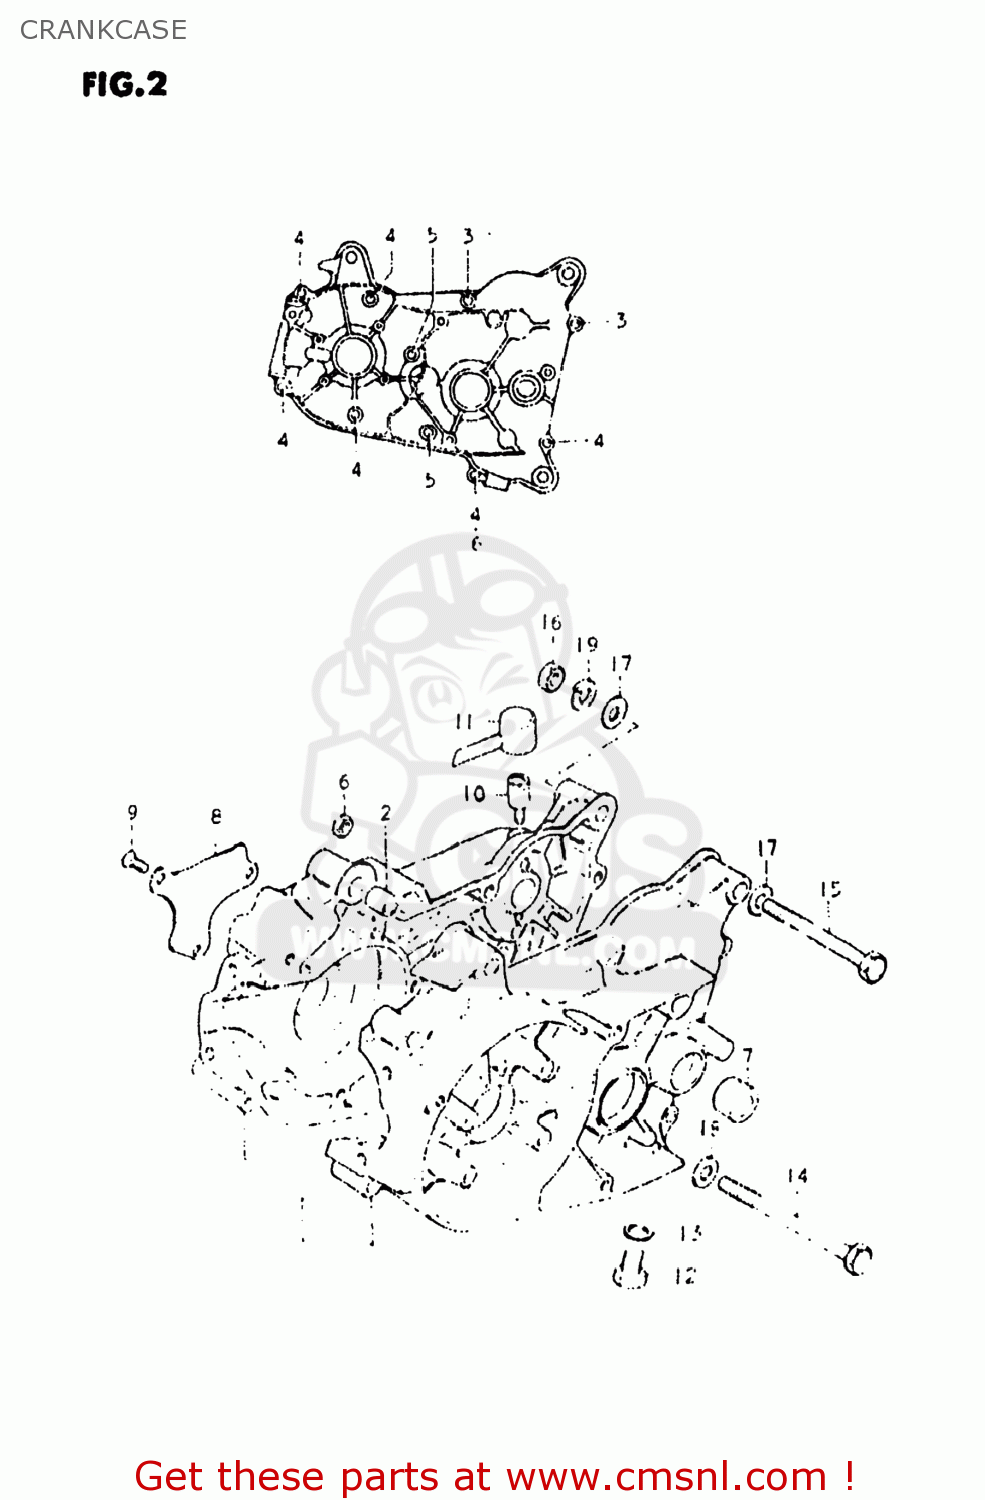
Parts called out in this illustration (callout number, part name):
1	CRANKCASE ASSEMBLY
2	PIN
3	SCREW 6X30
4	SCREW (6X35)
5	SCREW
6	NUT
7	BUSH
8	PLATE,OIL RESERVOIR
9	SCREW
10	PLUG,TRANSMISSION BREATHER
11	GASKET (NAS)
12	PLUG
13	GASKET(10X14X3.6) (NAS)
14	BOLT
15	BOLT
16	NUT
17	WASHER
18	WASHER
19	LOCK WASHER
